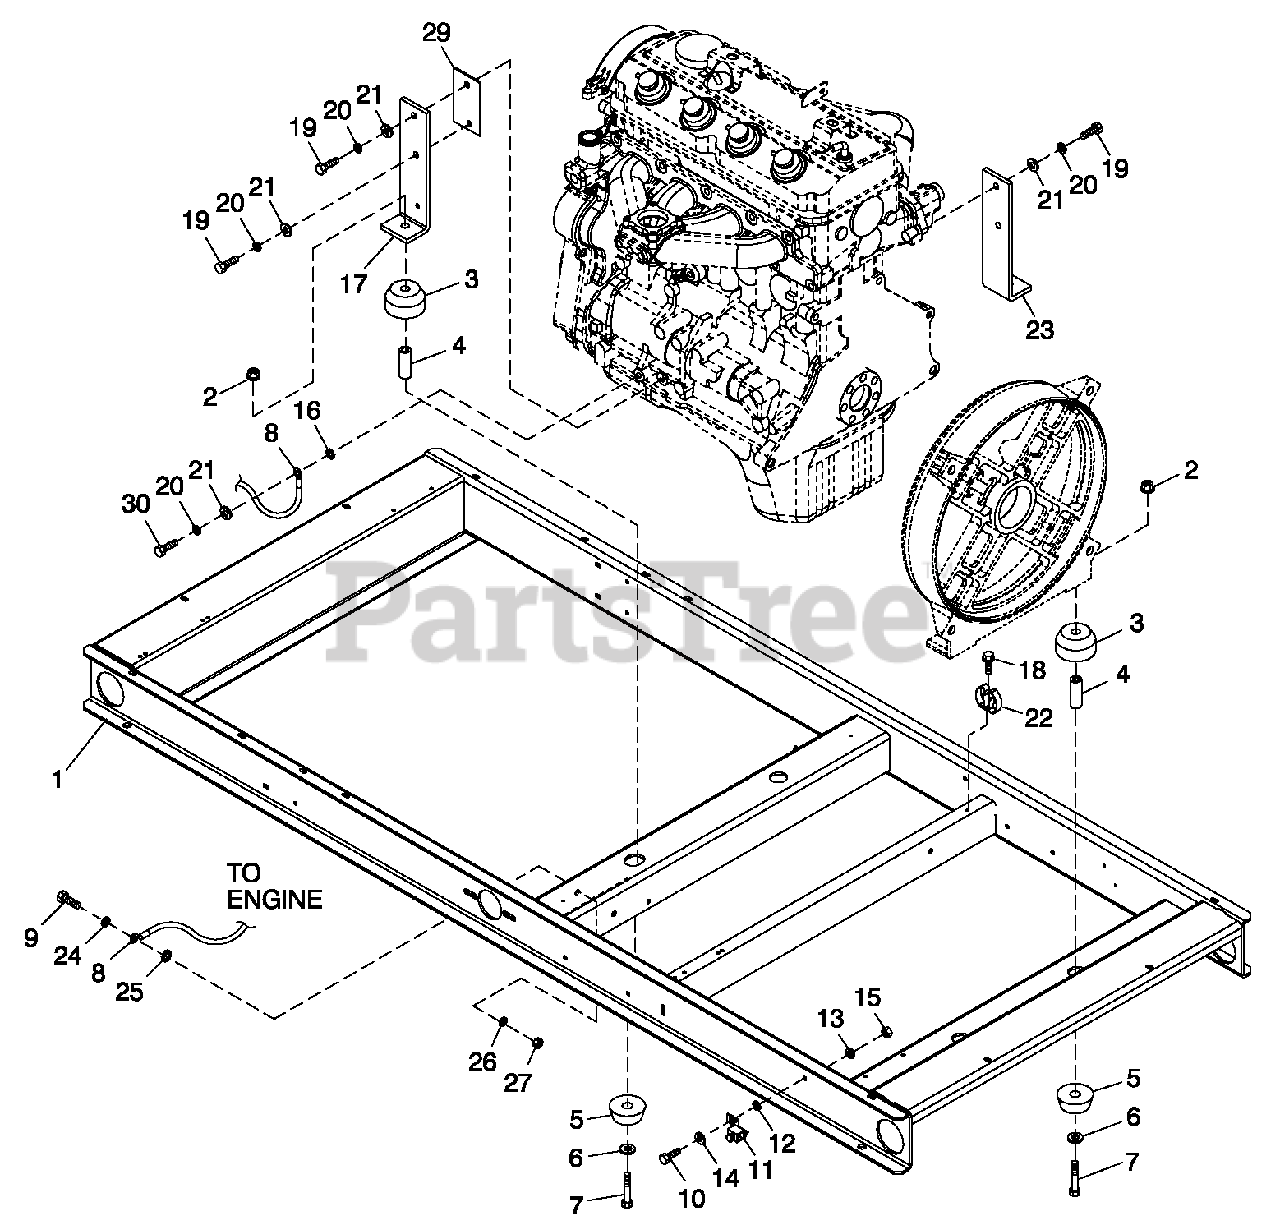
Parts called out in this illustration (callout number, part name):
1	WELDMENT FRAME 2.4L C2 60KW
2	NUT FLANGED HEX M12-1.75
3	DAMPENERVI B RATION 40 BLUE
4	SPACER .49 X .62 X 1.87 PWDR/ZNC
5	DAMPENERVI B RATION
6	WASHER FLAT M12
7	SCREW HHC M12-1.75 X 80 G8.8
8	ASSY W IRE 14.00"
9	SCREW HHC M8-1.25X 30 G8.8
10	SCREW HHC M6-1.0X 16 G8.8
11	LUG SLDLSS #2-#8X 17/64 CU
12	WASHER SHAKEPROOFI NT 1/4
13	WASHER LOCK M6-1/4
14	WASHER FLAT M6-1/4ZINC
15	NUT HEX M6 -1.0 G8YEL CHR
16	WASHER SHAKEPROOF I NT 3/8
17	SUPPORT LH ENGINE 2.4L
18	SCREW HHTT M4-0.7X8BP
19	SCREW HHC M10-1.25 X 30 G8.8
20	WASHER LOCK 7/16
21	WASHER FLAT 3/8-M10ZI NC
22	SPRING CL IP HOLDER .37-.62
23	SUPPORT RH ENG INE 2.4L
24	WASHER LOCK M8-5/16
25	WASHER SHAKEPROOF I NT 5/16
26	WASHER FLAT 5/16-M8ZINC
27	NUT HEX M8-1.25 G8 CLEAR Z I NC
29	SPACER LH ENGINE MOUNT
30	SCREW HHC M10-1.25 X 25 C8.8
